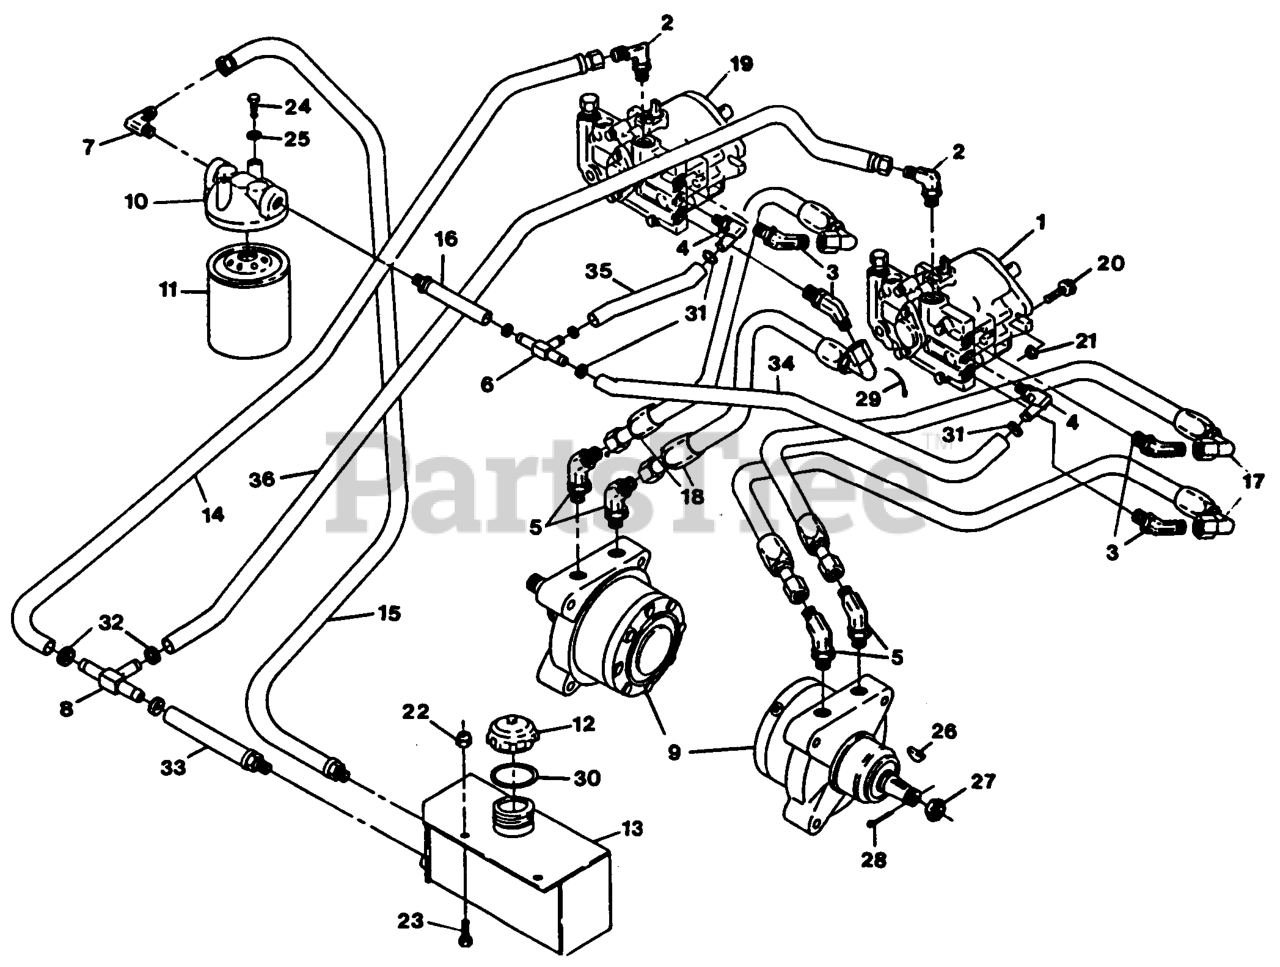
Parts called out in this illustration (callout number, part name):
2	FITTING-90 DEG
3	FITTING-HYD, 45 DEG
4	FITTING
5	FITTING-HYD, 45 DEG
6	FITTING-TEE, HOSE
8	FITTING-TEE, HOSE
10	FILTER-HEAD
14	LOW PRESSURE HOSE ASM
18	HOSE,HIGH PRESSURE
25	WASHER-LOCK
28	PIN-COTTER
29	TIE-PLASTIC
30	GASKET-CAP, TANK
31	CLAMP-HOSE
34	HOSE,LO PRESSURE
